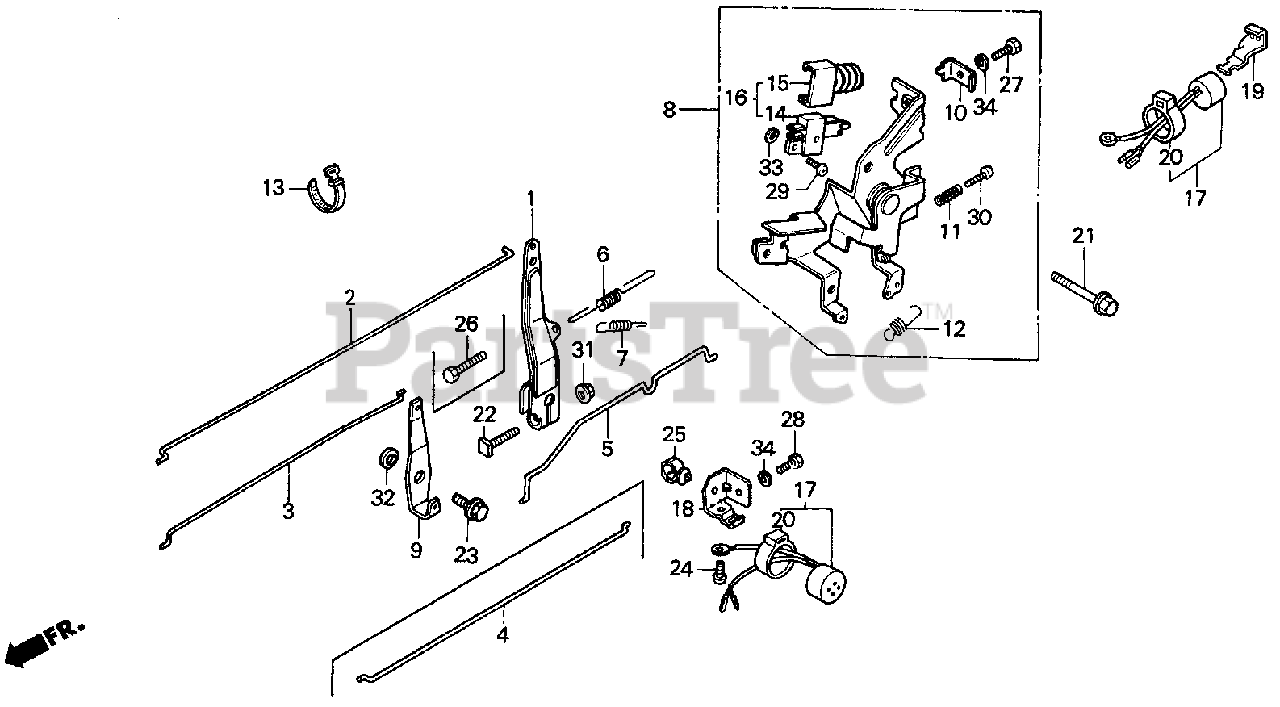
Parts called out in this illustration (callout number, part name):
1	ARM, GOVERNOR
2	ROD, GOVERNOR
3	ROD, CHOKE
4	ROD, JOINT
5	ROD, JOINT
6	SPRING, GOVERNOR
7	SPRING, GOVERNOR PRIMARY
8	CONTROL ASSY.
9	LEVER, CHOKE JOINT (Honda Code 2090199). (NOT AVAILABLE)
10	HOLDER, CABLE
11	SPRING, CONTROL ADJUSTING
12	SPRING, CABLE RETURN
14	SWITCH ASSY., ENGINE
16	SWITCH ASSY., ENGINE STOP
21	BOLT, FLANGE (6X12) (CT200)
22	BOLT, GOVERNOR ARM
23	BOLT, FLANGE (6MM)
27	BOLT, RECESSED (5X16)
29	SCREW, PAN (4X14)
30	SCREW, PAN (5X20)
31	NUT, FLANGE (6MM)
32	WASHER, PLAIN (6MM)
33	WASHER, SPRING (4MM)
34	WASHER, SPRING (5MM)
